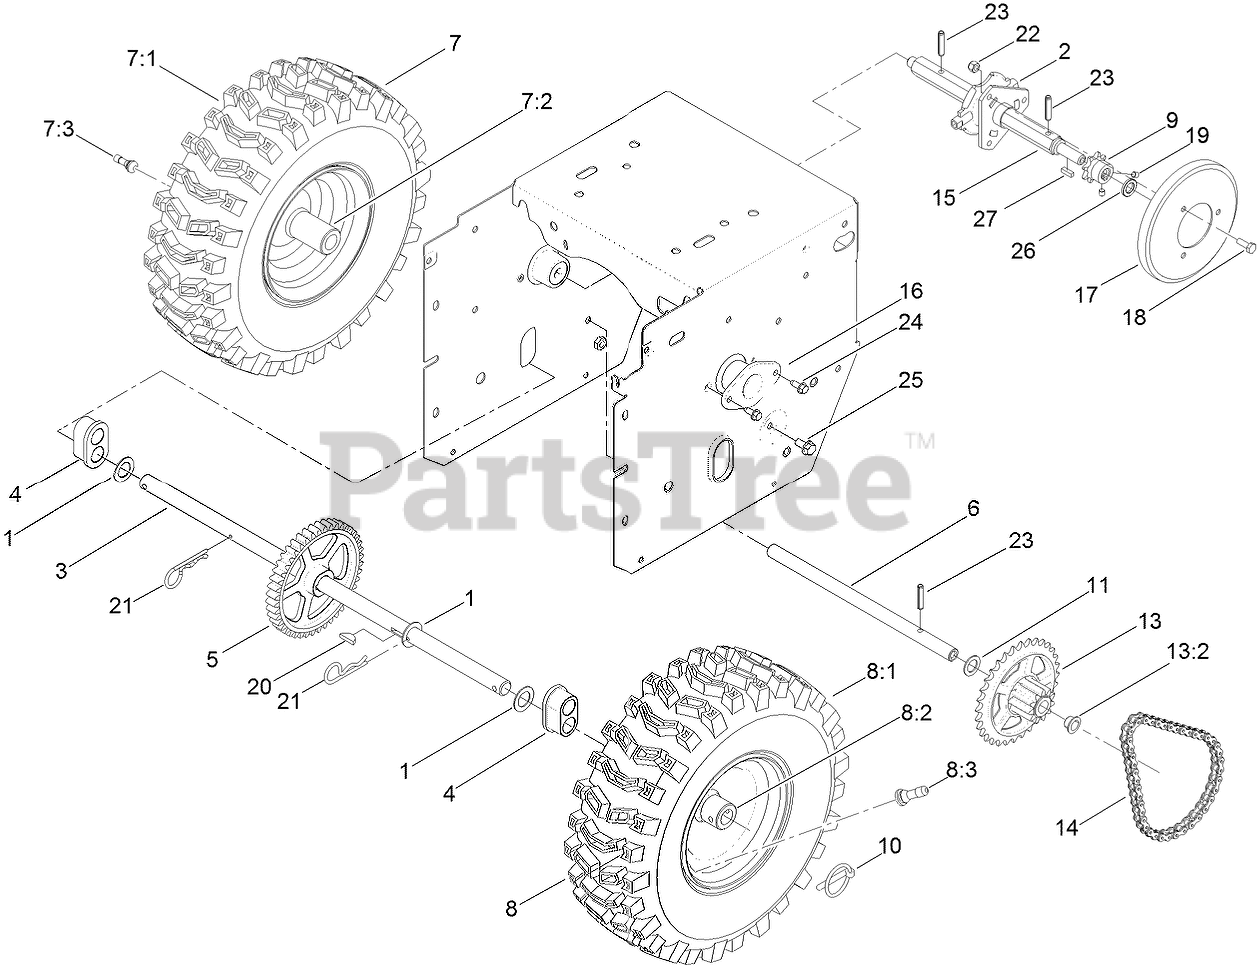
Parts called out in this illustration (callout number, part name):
1	WASHER-THRUST
2	TRUNNION-HEX
3	SHAFT-AXLE
4	BEARING-AXLE
5	GEAR-AXLE, 44 TOOTH
6	SHAFT-INTERMEDIATE
7	RH WHEEL AND TIRE ASM
7:2	RIM-TIRE
7:3	STEM-VALVE
8	LH WHEEL AND TIRE ASM
8:2	RIM-TIRE
8:3	STEM-VALVE
9	SPROCKET-8 TOOTH
10	KLIK PIN ASM
11	WASHER-FLAT
13	SPROCKET ASM
13:2	BUSHING-FLANGE
14	CHAIN-ROLLER
14	LINK-CONNECTING
15	SHAFT-HEX
16	RETAINER-BEARING
17	WHEEL-FRICTION
18	SCREW-HH
19	SCREW-HSH
20	KEY-WOODRUFF
21	PIN-HAIR
22	NUT-LOCK, NI
23	PIN-ROLL, SLOTTED
24	SCREW-HWH
25	SCREW-HWHTF
26	SPACER-BUSHING
27	KEY-SQUARE
